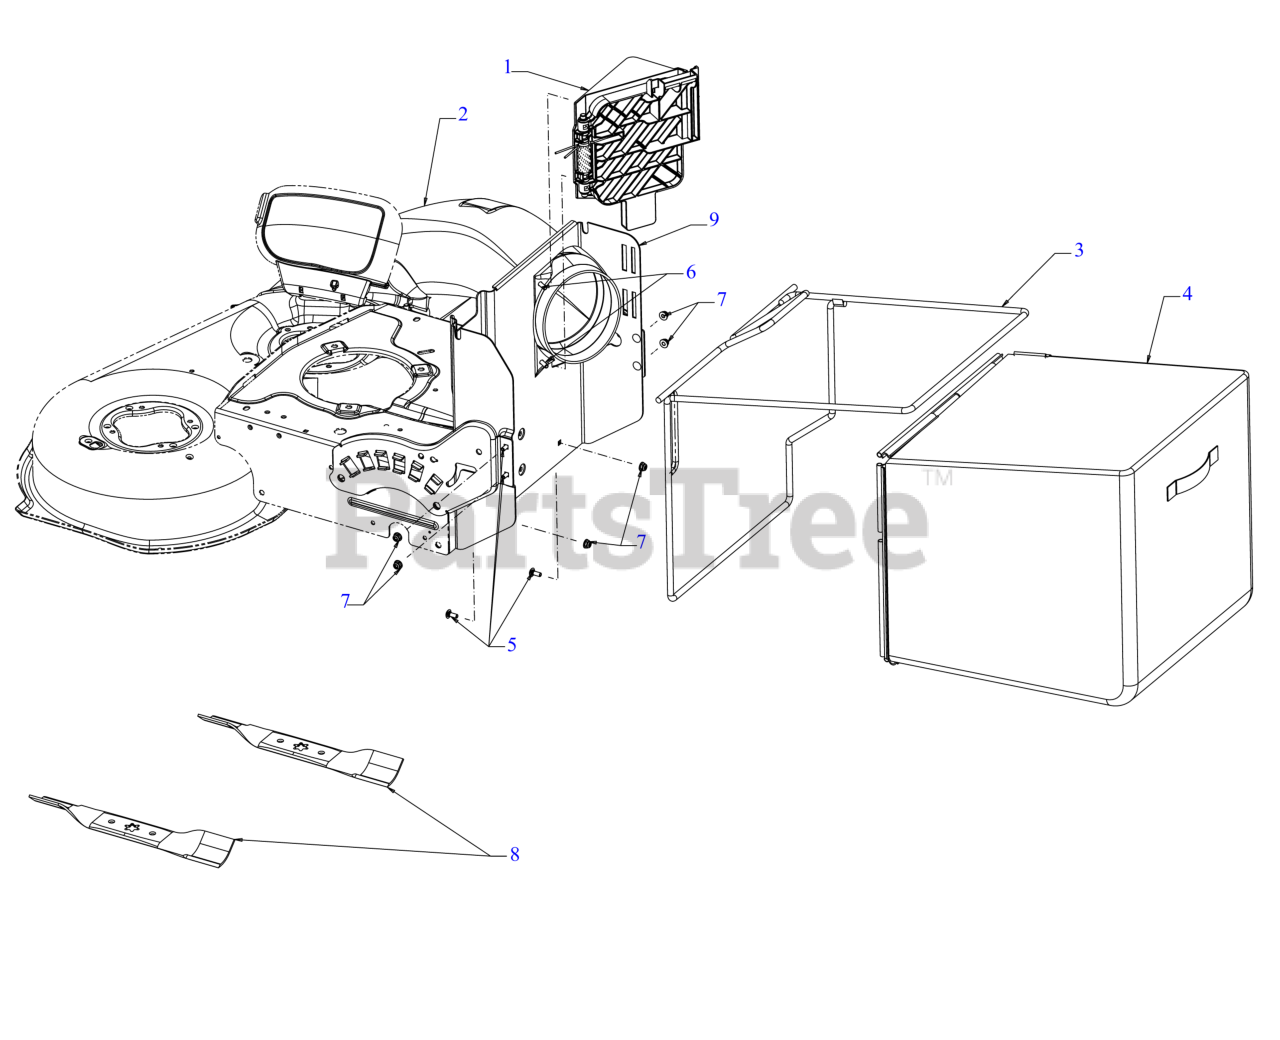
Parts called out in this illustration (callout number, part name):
1	GRASSBAG DOOR ASSEMBLY
2	CHUTE ASSEMBLY
3	GRASSBAG FRAME (POWDER BLACK)
4	28" GRASSBAG
5	CARRIAGE BOLT 1/4-20 x .62
6	SCREW 1/4 x .750
7	FLANGE LOCK NUT
8	BLADE (HI LIFT) (14.2)
9	GRASSBAG SUPPORT BRACKET (POWDER BLACK)
